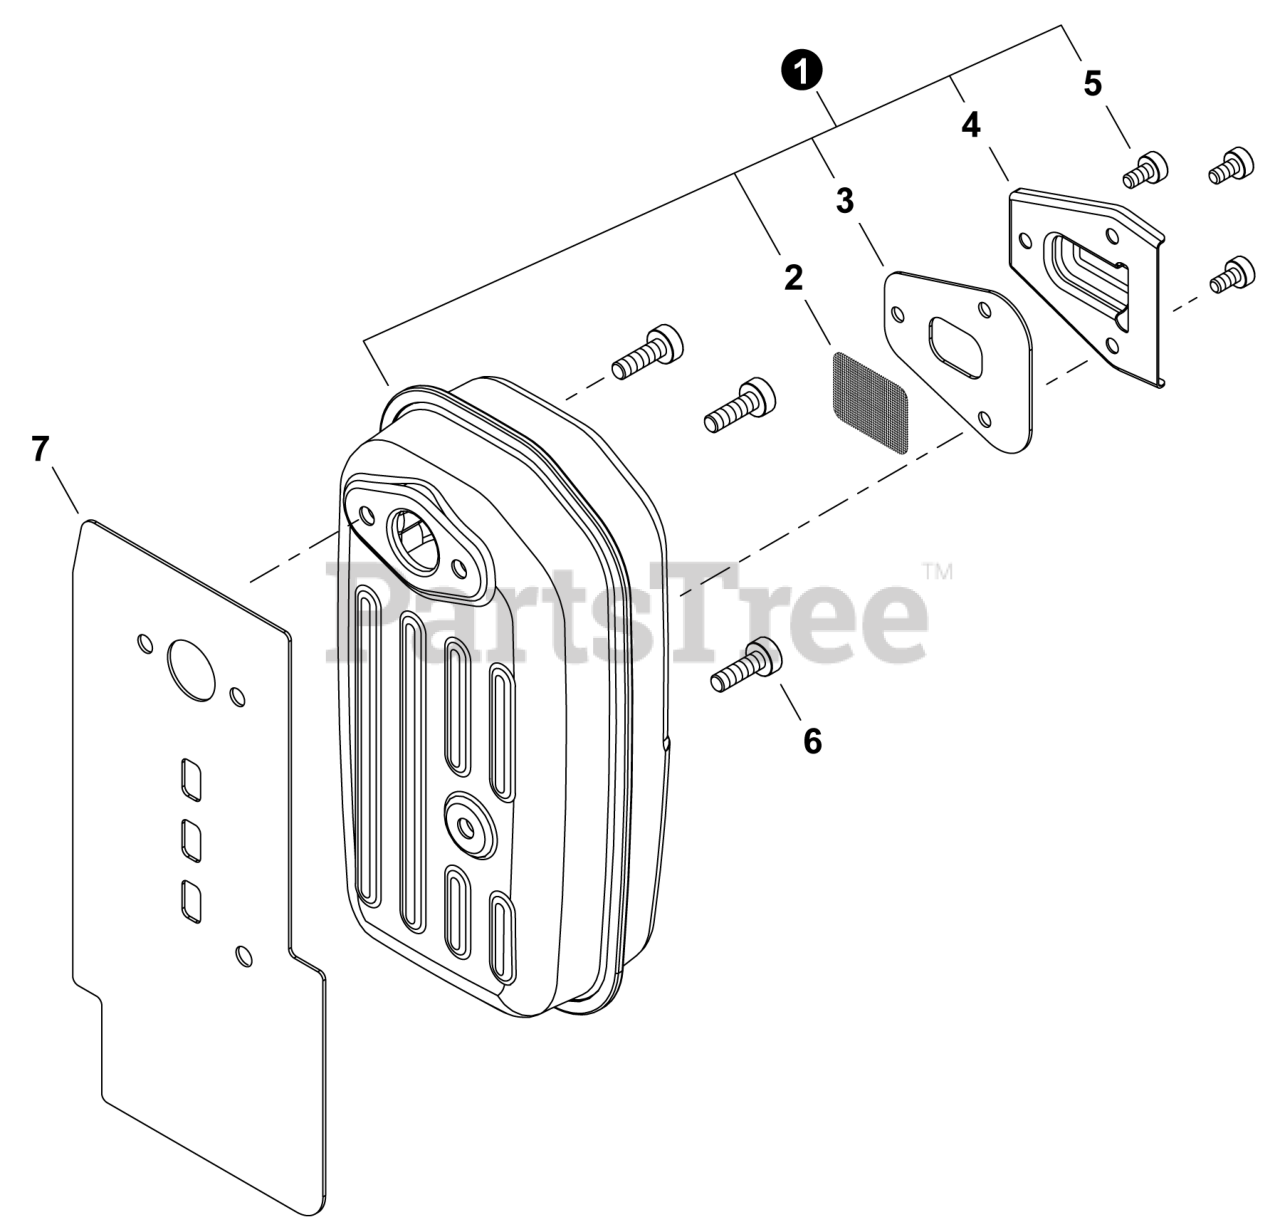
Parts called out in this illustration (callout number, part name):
1	MUFFLER ASSY
2	SCREEN, SPARK ARRESTER
3	GASKET, EXHAUST
4	GUIDE, EXHAUST
5	BOLT, TORX 4x8
6	BOLT, TORX 5x16
7	GASKET, EXHAUST
